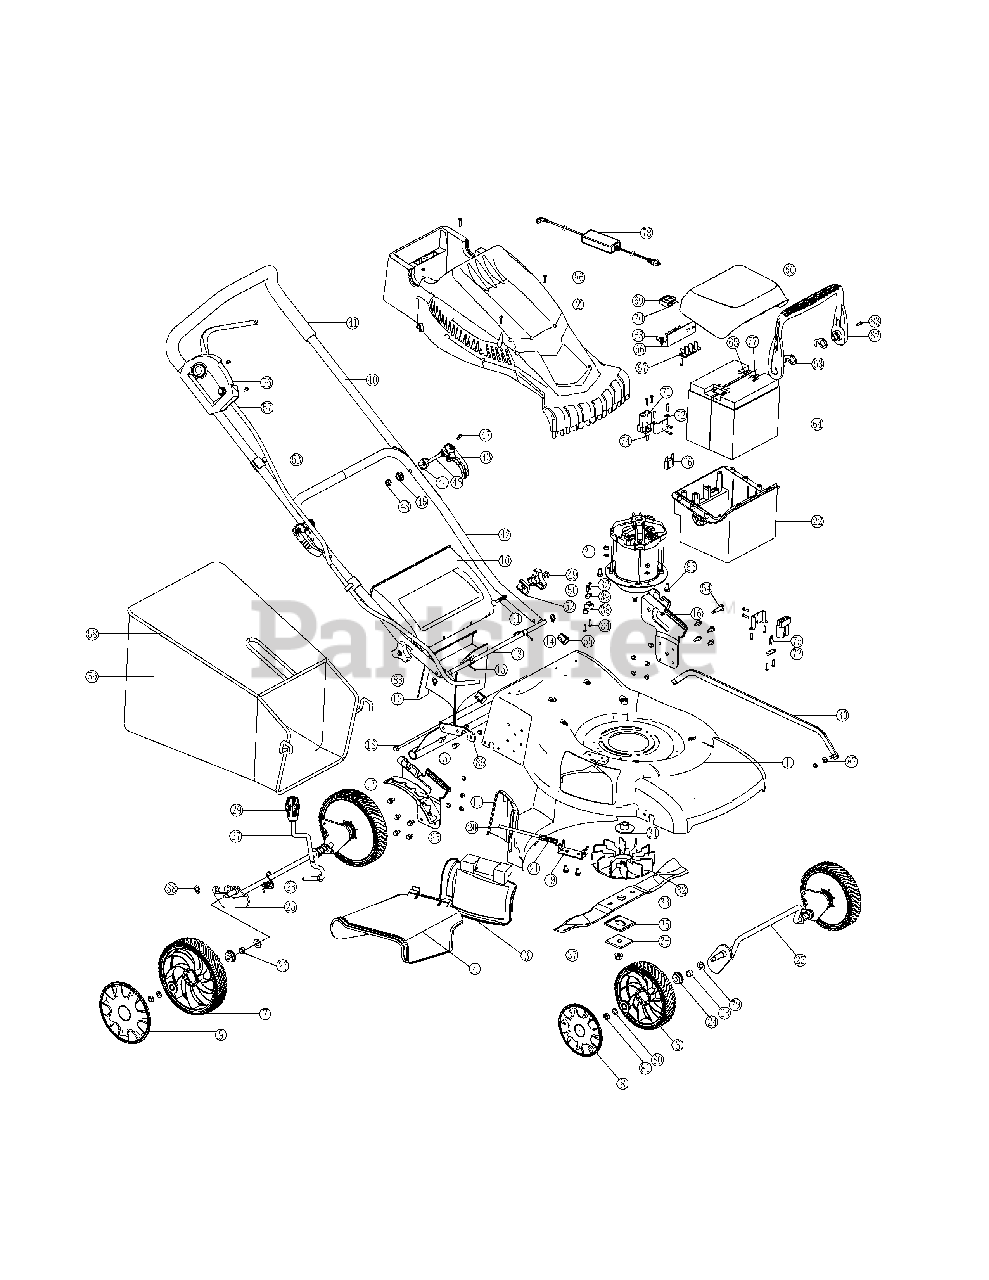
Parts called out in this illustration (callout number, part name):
1	Deck
3	Side Discharge Door
4	Side Discharge Chute
5	Trail Shield
6	Front Wheel
7	Rear Wheel
11	Rear Baffle
12	Mulching Plug
13	Rear Shaft
16	Left Bracket
17	Right Bracket
18	Trail Shield Pin
19	Side Discharge Bracket
20	Side Discharge Pin
22	Front Shaft Assembly
23	Front Shaft Bushing
25	Rear Shaft Assembly
26	Rear Shaft Bushing
27	Handle Adjust
28	Handle Adjust Spring
29	Handle Adjust Knob
31	Motor
39	Strain Relief
40	Upper Handle
41	Handle Grip
42	Lower Handle
43	Quick Release
45	Quick Release Knob
47	Quick Release Pin
49	M6 Lock Nut
56	Switch Box
60	Battery Pack Cover
61	Battery Pack Housing
67	PCB Support
68	Connector
69	Safety Key
70	Key Connector
71	SA50 Connector
80	8mm Washer
82	ST4.2x16 Screw
83	ST4.2x25 Screw
84	ST4.8x16 Screw
85	M6x12 Screw
86	M5 x 12 Screw
88	10mm Lock Ring
